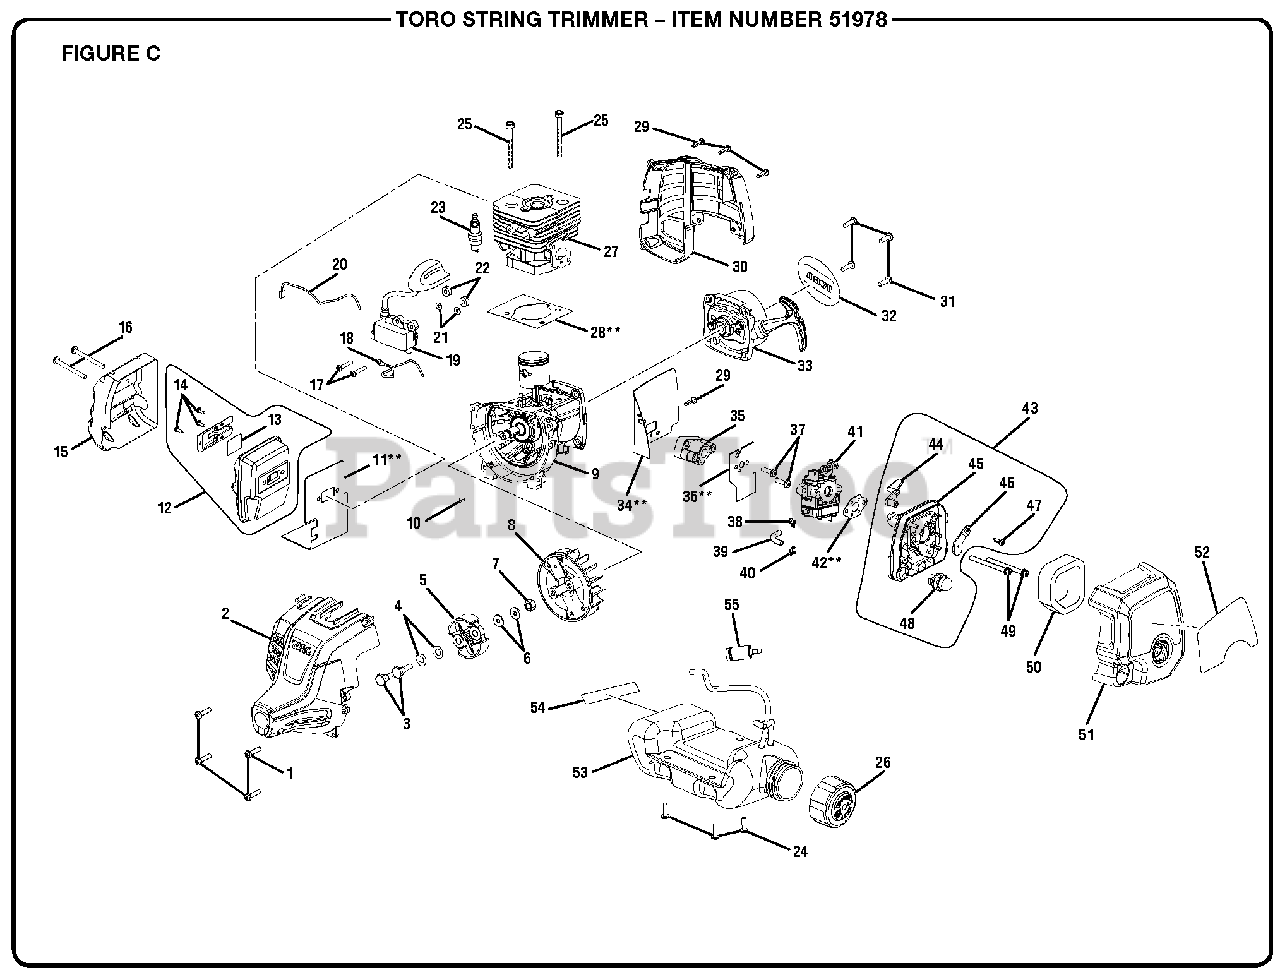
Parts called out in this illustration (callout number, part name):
1	Screw (M5 x 20 mm, T20 Torx Pan Hd.)
2	Front Housing Assembly
3	Clutch Shoulder Bolt (M6 x 22.5 mm, Hex Hd.)
4	Curved Washer
5	Clutch Assembly
6	Washer (ID6 x OD15 x 1.2t)
7	Flywheel Nut
9	Crankcase Assembly
10	Woodruff Key (10 mm x 3 mm)
11	Muffler Gasket
12	Muffler Assembly
13	Screen
14	Screw (6-20 x 1/4 in., T20 Torx Pan Hd. S.T.)
15	Heat Shield
16	Screw (M5 x 50 mm, T25 Torx Soc. Hd.)
17	Screw w/Washer (M4 x 22 mm, T20 Torx Soc. Hd.)
18	Lead Wire (Red)
19	Coil Boot Assembly
20	Lead Wire (Black)
21	Washer (ID4.2 x OD10 x1t)
22	Spacer (Phenolic)
23	Spark Plug (Champion RCJ4)
24	Screw (M5 x 16 mm, T25 Torx Soc. Hd.)
25	Screw (M5 x 22 mm, T25 Torx Soc. Hd.)
26	Fuel Cap Assembly
28	Gasket
29	Screw (M4 x 18 mm, T20 Torx Pan Hd. S.T.)
30	Rear Engine Housing
31	Screw w/Washer (M5 x 16 mm, T25 Torx Soc. Hd.)
32	Logo Label (Rear)
33	Starter Recoil & Starter Cup Assembly
34	Insulator Gasket
35	Heat Dam Insulator
36	Gasket
37	Screw w/Washers (M5 x 34 mm, T25 Torx Pan Hd.)
38	Hose Clip
39	Fuel Line (45 mm)
40	Hose Clip
41	Carburetor Assembly
42	Carburetor Gasket
43	Airbox Base Assembly
44	Choke Lever
45	Airbox Base
46	Choke Plate
47	Screw (M4 x 12 mm, T20 Torx Pan Hd. S.T.)
48	Primer Assembly
49	Screw (M5 x 60 mm, T25 Torx Cap Soc. Hd.)
50	Air Filter
51	Airbox Cover Assembly w/Label
52	Starting Instructions Label
53	Fuel Tank & Cap Assembly
54	Combustion Warning Label
55	Fuel Filter
